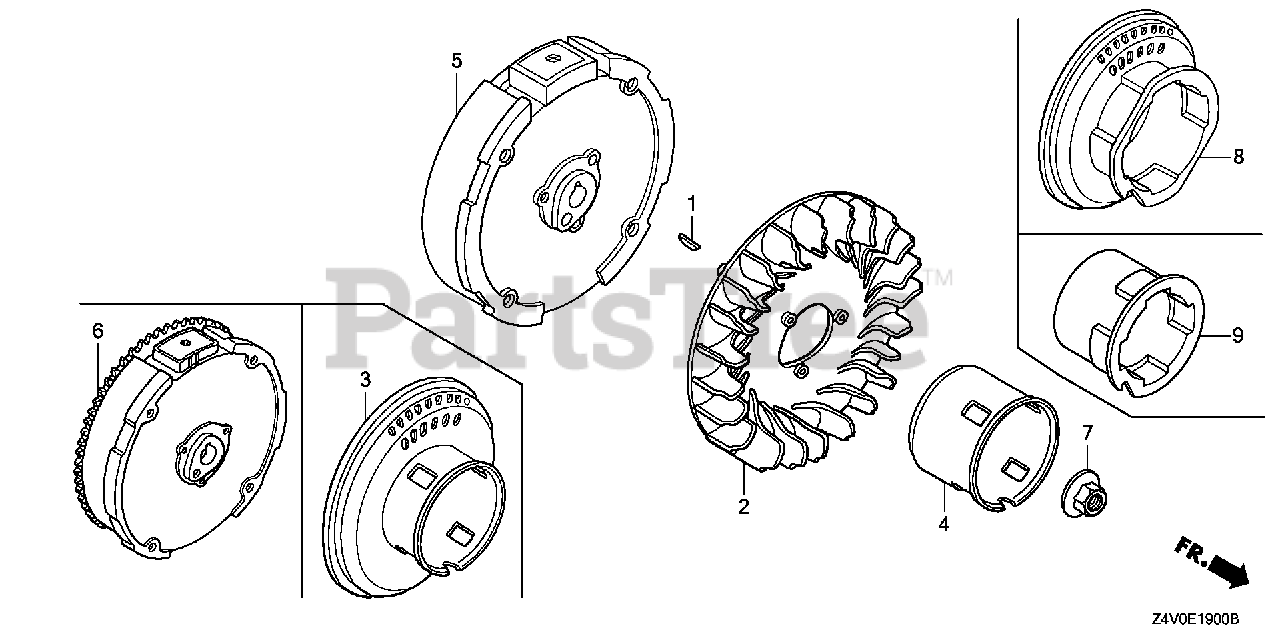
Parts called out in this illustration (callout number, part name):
1	KEY, SPECIAL WOODRUFF (25X18)
2	FAN, COOLING
6	FLYWHEEL (SEL-7A)
7	NUT, SPECIAL (14MM)
9	PULLEY, STARTER
